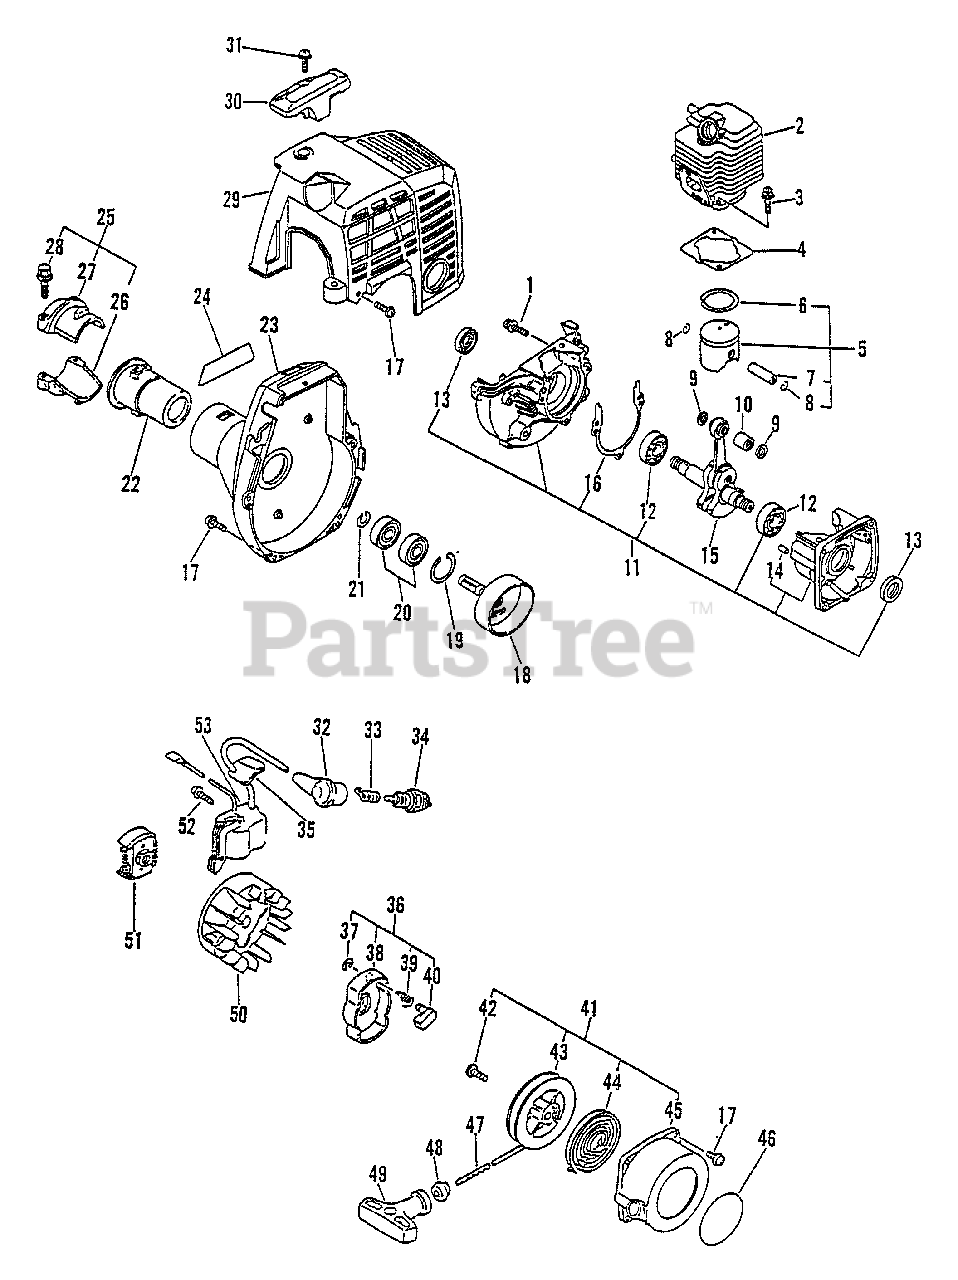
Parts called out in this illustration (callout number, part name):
1	SCREW - 5X28
2	CYLINDER
3	SCREW - 5X22
4	GASKET, CYLINDER
5	PISTON KIT
6	RING, PISTON
7	PIN, PISTON
8	RING, RETAINING
9	SPACER, PISTON
10	BEARING, NEEDLE
11	CRANKCASE KIT
12	BEARING, BALL - 6201
13	SEAL, OIL
14	PIN - LOCATING
15	CRANKSHAFT ASSY
16	GASKET, CRANKCASE
17	SCREW - 4X16
18	DRUM, CLUTCH
19	RING, RETAINING - 28
20	BEARING, BALL - 6001
21	RING, RETAINING - 12
23	FAN CASE ASSY
24	LABEL - MODEL PE-2400
25	HOLDER KIT
26	CLAMP, MAIN PIPE
27	CLAMP, MAIN PIPE - UPPER
28	BOLT - 5X25
29	COVER, ENGINE
30	GUARD - TOP
31	SCREW - 5X16
32	CAP, SPARK PLUG
33	TERMINAL, SPARK PLUG CAP
34	SPARK PLUG -- BPM-7A
36	STARTER PAWL ASSY
37	RING, RETAINING - 4
38	CATCHER, PAWL
39	SPRING, RETURN
40	PAWL, STARTER
41	STARTER ASSY
43	REEL, ROPE
44	SPRING, REWIND
45	CASE, STARTER
46	LABEL - ECHO
47	ROPE, STARTER - 3X890
48	GUIDE, ROPE
49	GRIP, STARTER
50	FLYWHEEL
51	CLUTCH ASSY
52	SCREW - 4X22
53	COIL, IGNITION
